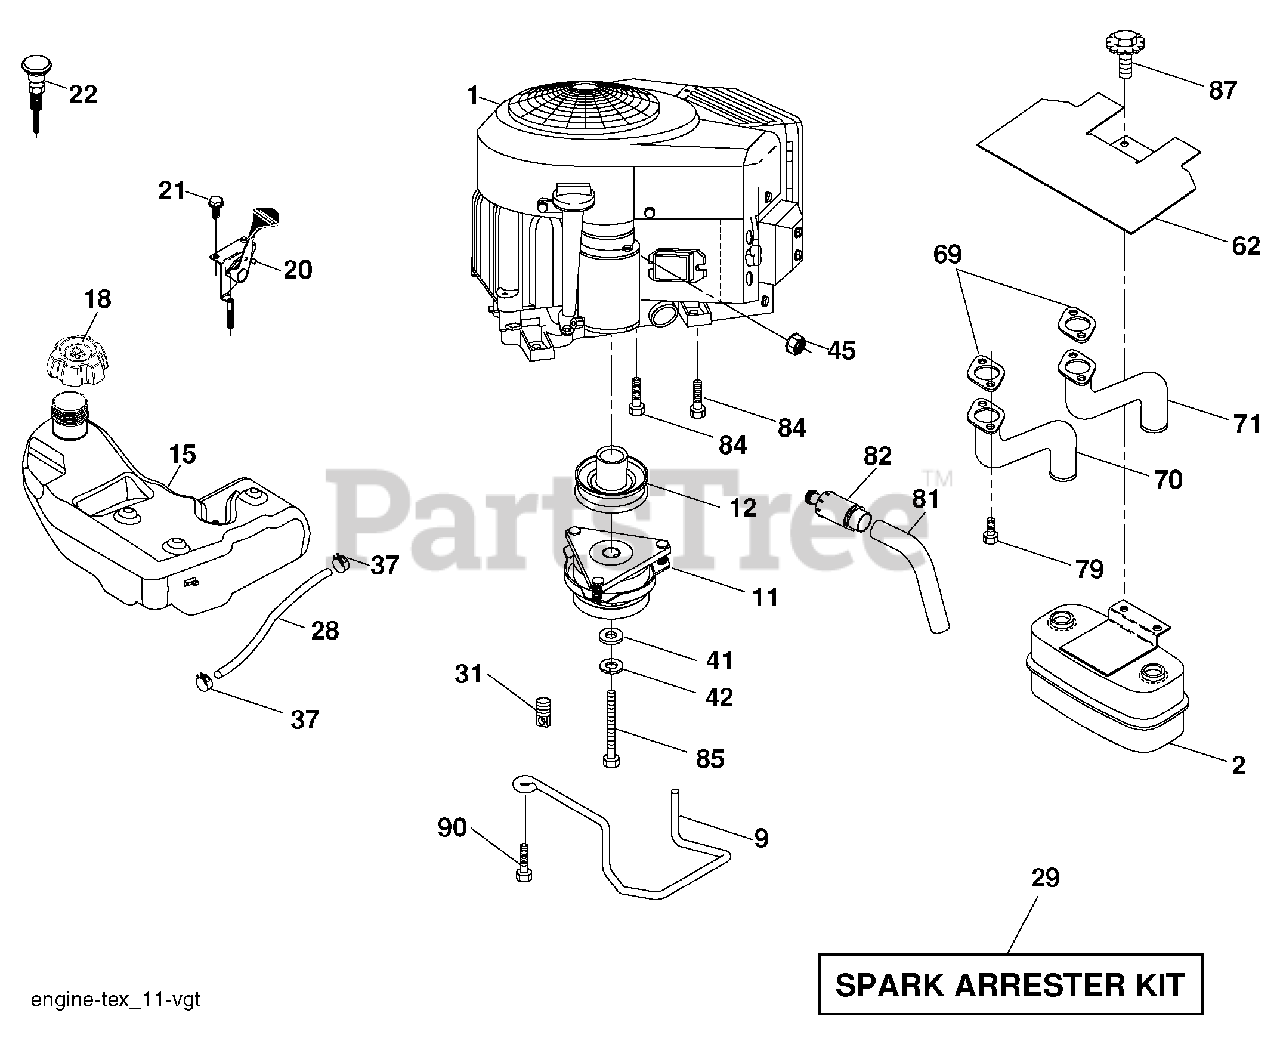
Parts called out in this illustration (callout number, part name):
2	Bracket Pivot Fender
3	Strap, Asm Fender
5	Clip, Push In, Hinged
6	Nut, Lock W/Ins. 3/8-16 unc
7	Spring, Seat Cprsn
8	Bolt 5/16-18 unc x 3/4 w/Sems
10	Pan, Seat
21	Bolt, Shoulder 5/16-18
37	Nut, Lock 5/16-18 unc
40	Handle Slide Seat
41	Spring Latch Seat
43	Bolt Fin Hex 3/8-16 unc x 3/4
44	Washer 13/32 x 2-3/8 x 12 Ga.
